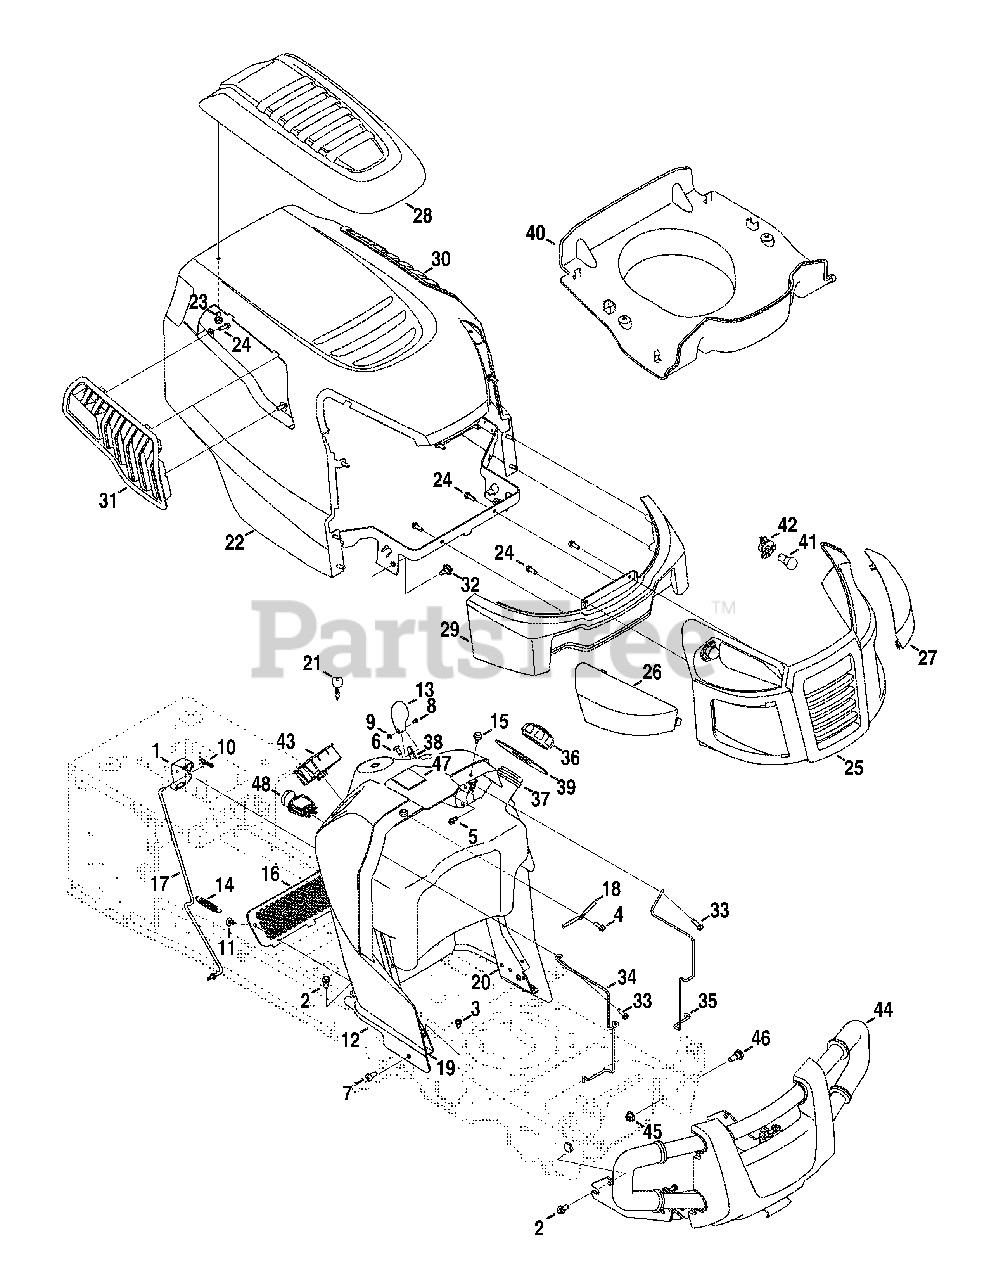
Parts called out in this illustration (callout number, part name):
1	Dash Lever
2	Taptite Screw, Lock Washer, 5/16-18:.750
3	Taptite Screw, Lock Washer, 1/4-20:0.500
4	Hi-Lo Screw, Lock Washer, 1/4-15:0.750
5	Screw, Lock Washer, 1/4-14:0.625
6	Screw, 1/4-14:0.625
7	Taptite Screw, 5/16-18:0.750
8	Machine Screw, #8-32:0.375
9	Hex Nut, #8-32:GRA
10	Bow-tie Cotter Pin
11	Ratchet Clip:.250 DIA
13	Control Knob
14	Extension Spring, .500 DIA X 2.733 LG
15	Bumper
16	Accessory Net
17	Control Rod Latch
18	Lever Rod
19	RH Dash Support Plate
20	LH Dash Support Plate
21	Keys (set of 2)
22	Hood Assembly
23	Hi-lo Screw, Lock Washer, 1/4-15:0.50
24	Screw, Lock Washer, 1/4 DIA:.750
26	RH Lens
27	LH Lens
28	Hood Scoop
29	Lower Grill
30	LH Hood Scoop
31	RH Hood Scoop
32	Shoulder Screw, .43X.29:TT:5/16-18
33	Taptite Screw, 1/4-20:0.750
34	RH Tank Support Rod
35	LH Tank Support Rod
36	Fuel Cap
37	Fuel Tank, 2.75 Gallons
38	Throttle/Choke Control
39	Fuel Tank Gasket
40	P-Style Plen
41	Miniature Lamp, 12V
42	Lamp Socket
43	Switch Key Module
44	Guard Assembly
45	Flangelock Nut, 3/8-16
46	Shoulder Bolt, .496 x .336:3/8-16
47	Hour Meter
48	PTO Switch
